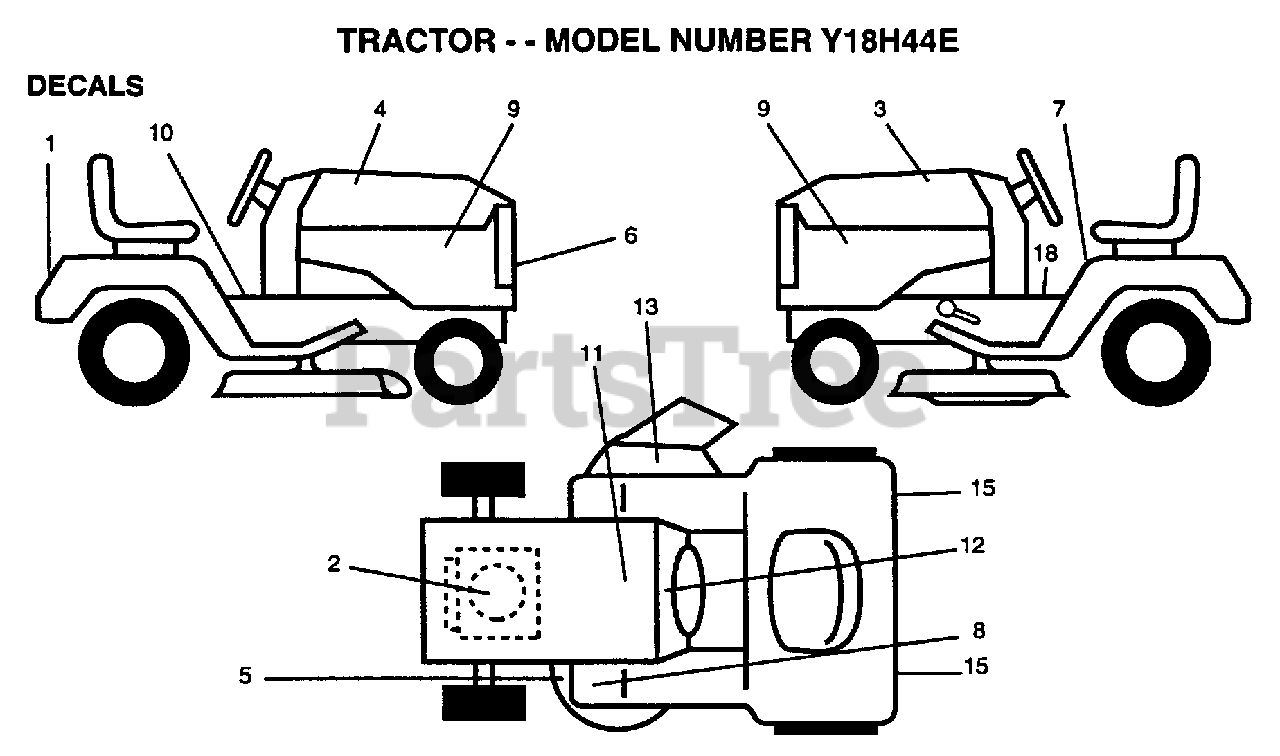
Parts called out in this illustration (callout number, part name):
2	"DECAL,HP ENGINE"
3	DECAL HOOD LH
5	"DECAL.V.BELT.44"""
6	DECAL.GRILL.YARDP
7	DECAL CAUTION
8	DECAL T
9	DECAL.PANEL.SIDE
10	DECAL BRAK PARK
11	DECAL.BATRY.3-3908
12	DECAL.DASH.INSTR.
13	"DECAL, WARNING"
15	REFLECTOR-TAIL YT
18	DECAL SADL HYDRO
